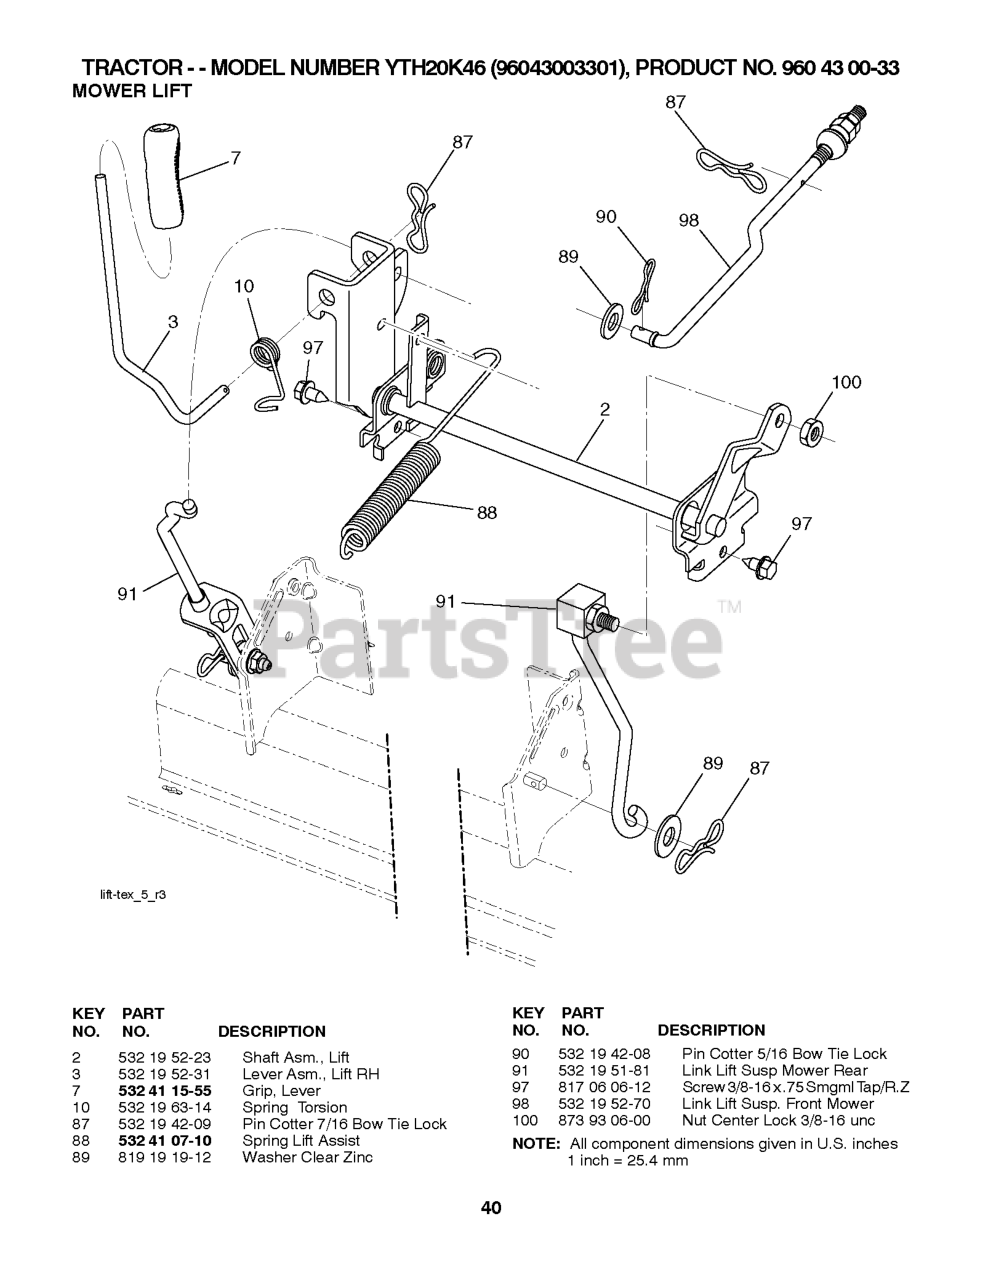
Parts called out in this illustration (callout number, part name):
2	SHAFT.ASM.LIFT.CROSS.H
3	LEVER.LIFT.HANDLE.LT
7	GRIP.HANDLE.LIFT.PVC.BLACK
10	SPRING.TORSION.LIFT.HANDLE
87	PIN.COTTER.7/16.BOW TI.
88	SPRING.LIFT.ASSIST
89	WASHER.CLEAR.ZINC
90	PIN.COTTER.5/16.BOW TI
91	LINK.ASM.LIFT.REAR
97	SCREW 3/8-16X3/4
98	LINK.ASM.SUSP.FRONT.MW
100	LOCKNUT
